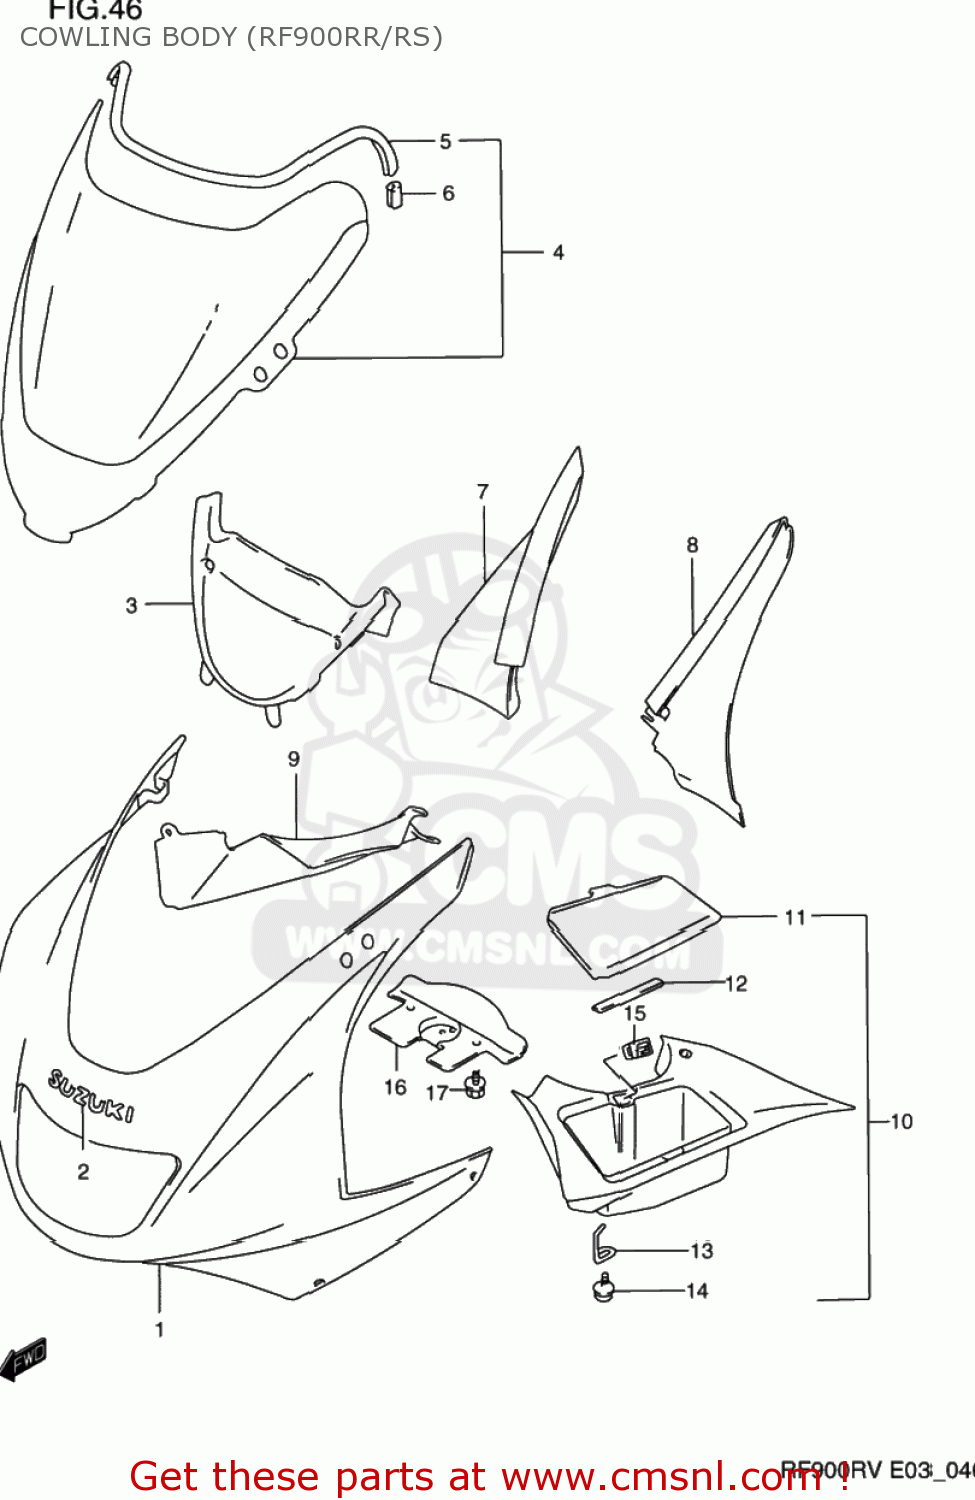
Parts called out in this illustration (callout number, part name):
1	COWLING ASSY,BODY
2	EMBLEM,SUZUKI
3	PANEL,COWLING CTR
4	WINDSCREEN SET
5	MOLDING WINDSCREEN
6	CLIP,WINDSCREEN MOLDING
7	PANEL,UPR,R
8	PANEL,UPR,L
9	PANEL,SIDE,R
10	PANEL ASSY,SIDE,L
11	LID,PANEL BOX
12	CUSHION,LID
13	HINGE,PANEL LID
14	SCREW
15	LOCK,I/P CTR BOX
16	COVER,COWLING FR LWR
17	BOLT(6X12)
